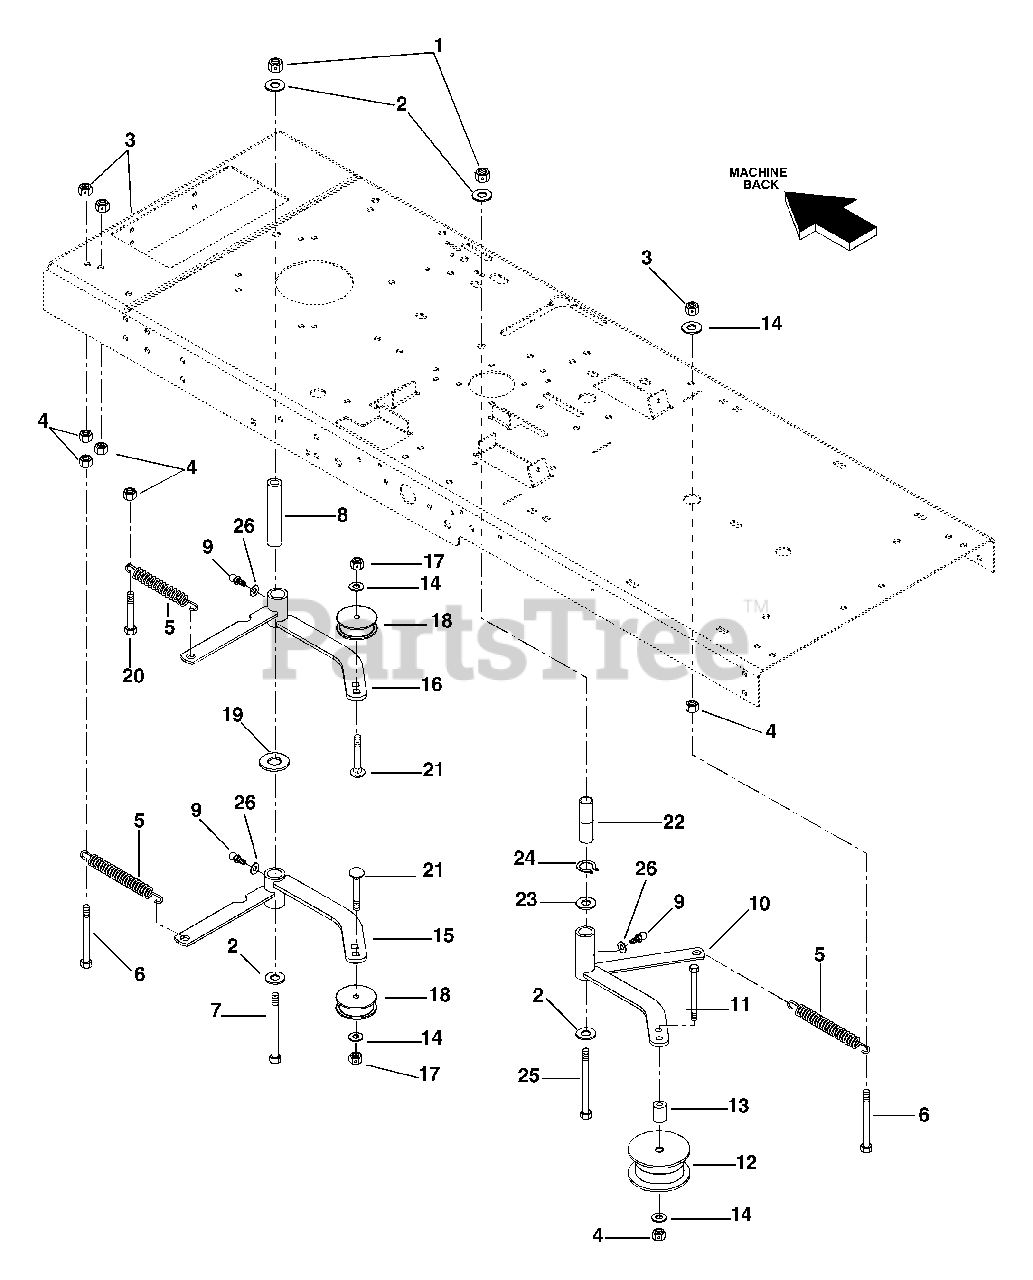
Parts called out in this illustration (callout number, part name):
1	Nut-Locking, Center .50-13
2	Washer-Flat, Steel .563 x 1.38 x .109
3	Nut-Locking, Center .38-16
4	Nut-Hex .38-16
5	Spring-Extension
6	Bolt-Hex .38-16 x 4.00 Grade 5
7	Bolt-Hex .50-13 x 5.50 Grade 5
8	Spacer-Idler Arm
9	Fitting-Lube .25-20 x .256
10	Weldment-Deck Idler Arm
10	Weldment-Idler Arm
11	Bolt-Hex .38-16 x 4.50
11	Bolt-Hex .38-16 x 2.50
12	Idler-4.0 inch Diameter
13	Spacer-Idler 48 inch (Models with 48" Decks)
14	Washer-Flat, Steel .406 x .812 x .065
15	Idler Arm Weldment Transaxle
16	Weldment-Jackshaft Idler Arm
17	Nut-Jam Lock .38-16
18	Idler-3.5 inch Diameter
19	Washer-Hardened
20	Bolt-Hex .38-16 x 1.75 Grade 5
21	Bolt-Round Head Square Shank .38-16 x 1.50
22	Spacer-Idler
23	Washer-.880 x 1.250 x .62
24	Ring-Retaining External .875 x .042
25	Bolt-Hex .50-13 x 4.50 Grade 5
26	Washer-Flat-Steel .250 x .562 x .049
